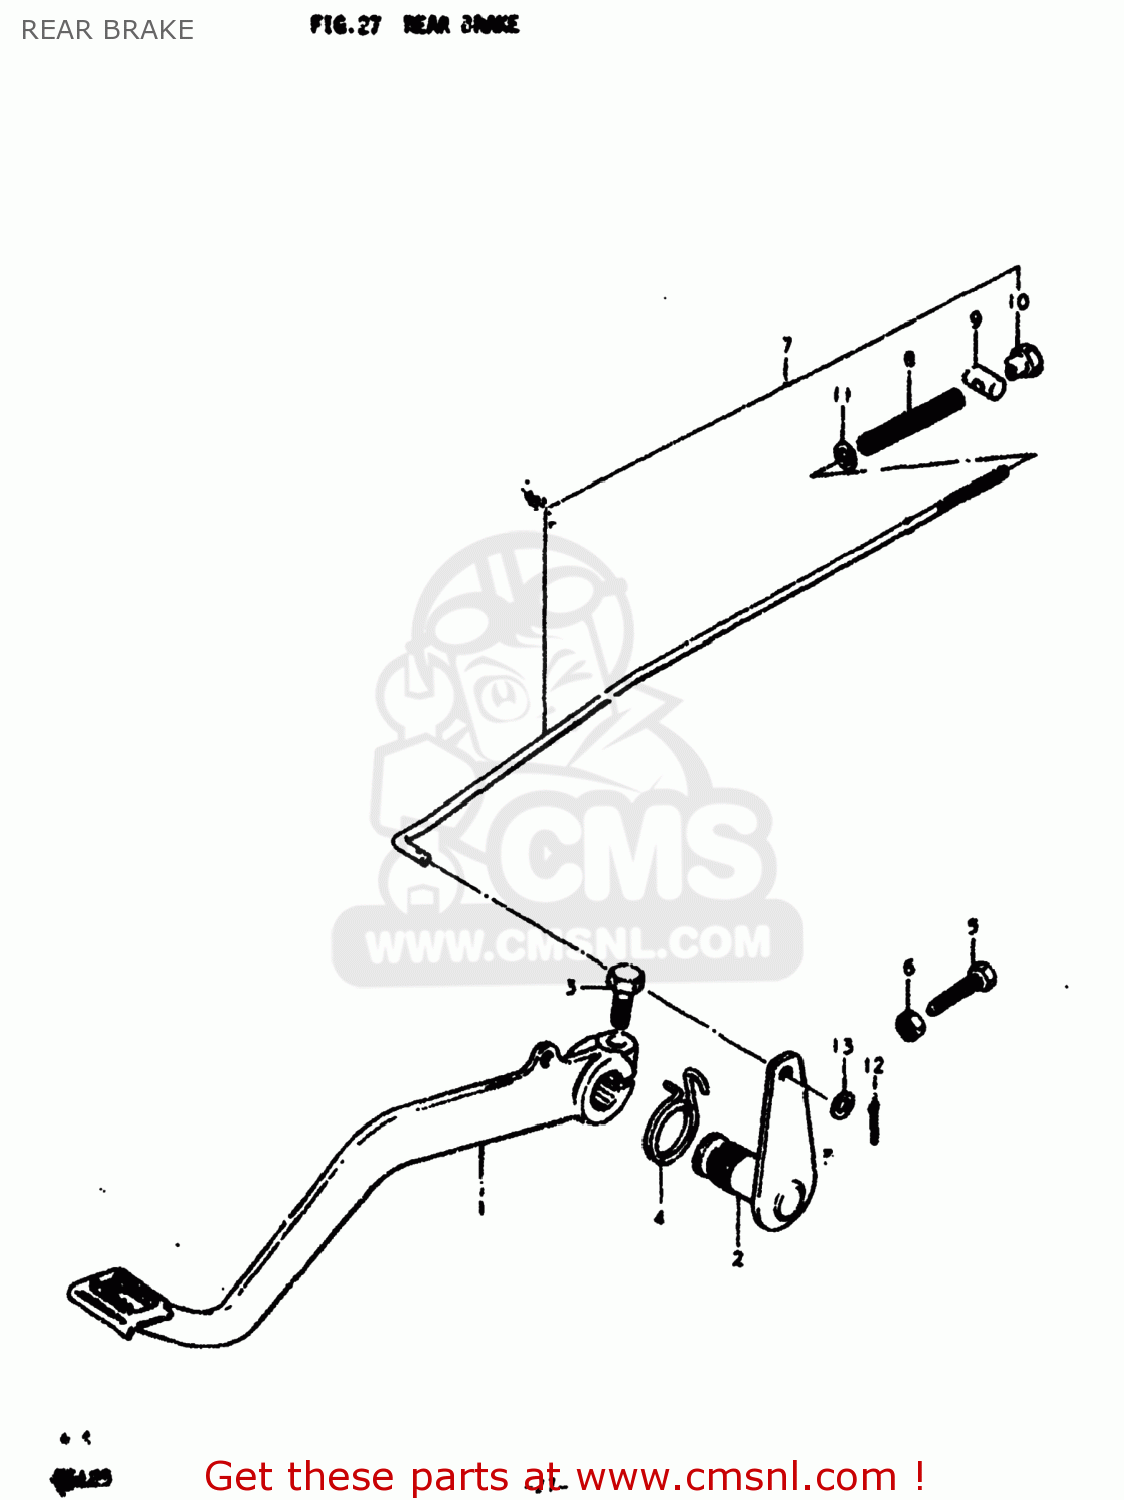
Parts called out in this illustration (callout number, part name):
1	PEDAL,BRAKE
2	ARM,BRAKE PEDAL ROD
3	BOLT
4	SPRING
5	BOLT(6X23)
6	NUT
7	ROD ASSEMBLY,REAR BRAKE
8	SPRING
9	PIN(11X18)
10	NUT
11	WASHER
12	PIN 20X20
13	WASHER
